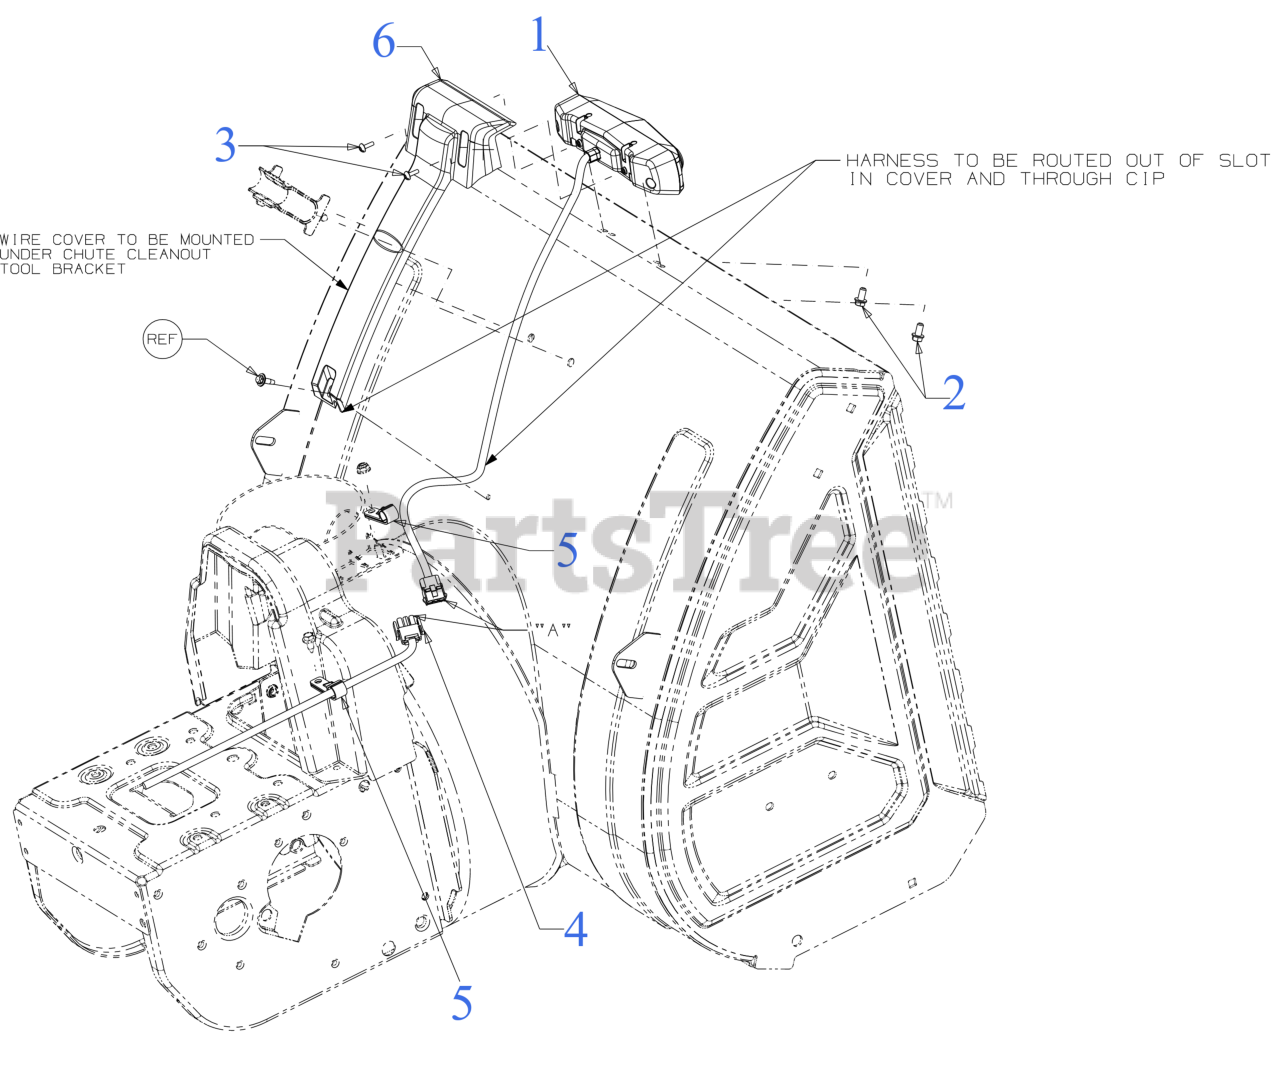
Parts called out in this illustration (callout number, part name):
1	LED LIGHT BAR HEADLIGHT ASSEMBLY
2	HEX SCREW 1/4-15 x .50
3	SCREW 8/16X.500
4	LED HEADLIGHT HARNESS
5	HEADLIGHT HARNESS CLAMP
6	LED LIGHT BAR COVER
